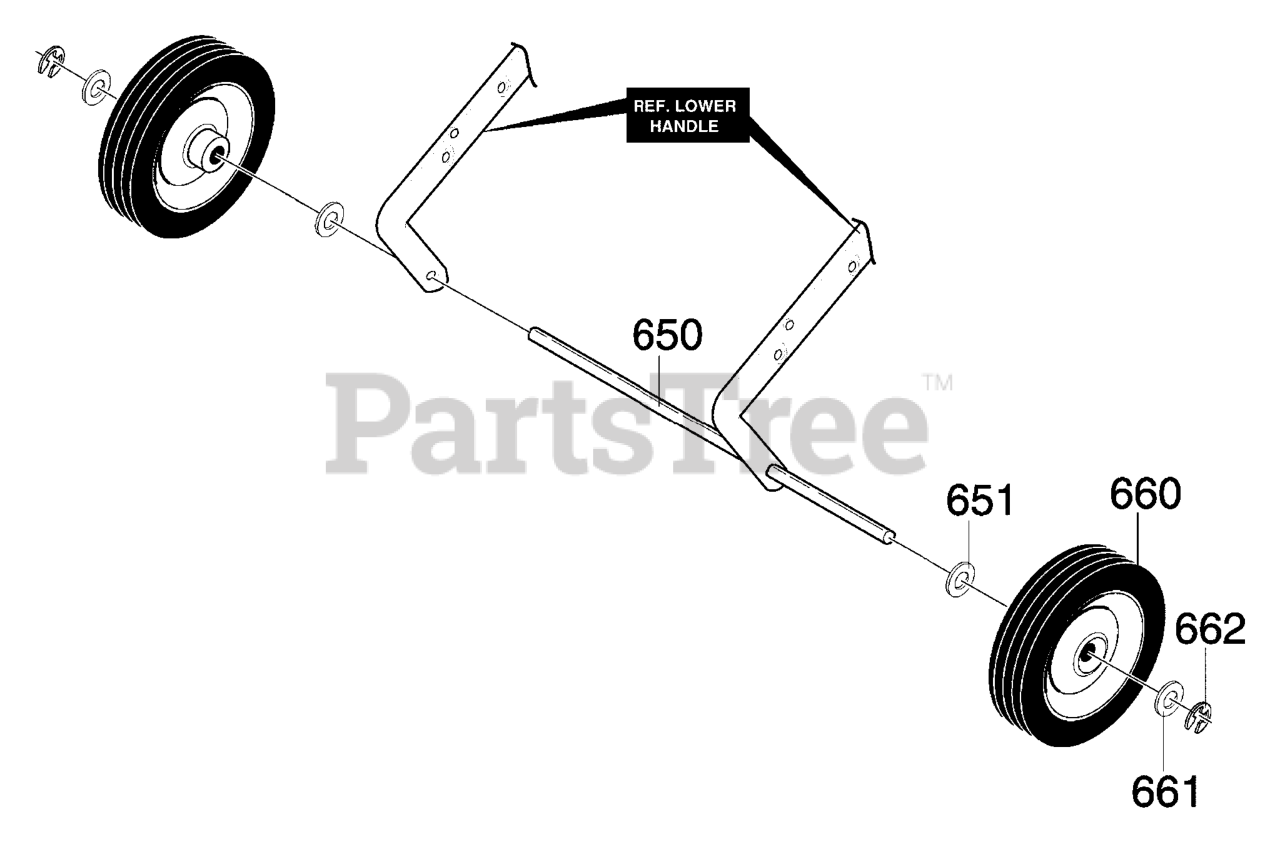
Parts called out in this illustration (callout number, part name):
650	AXLE SHAFT
651	WASHER, FLAT .391X1.00X1.25
660	TIRE & RIM
661	WASHER, FLAT .391X1.00X.125
662	RING, RET E
